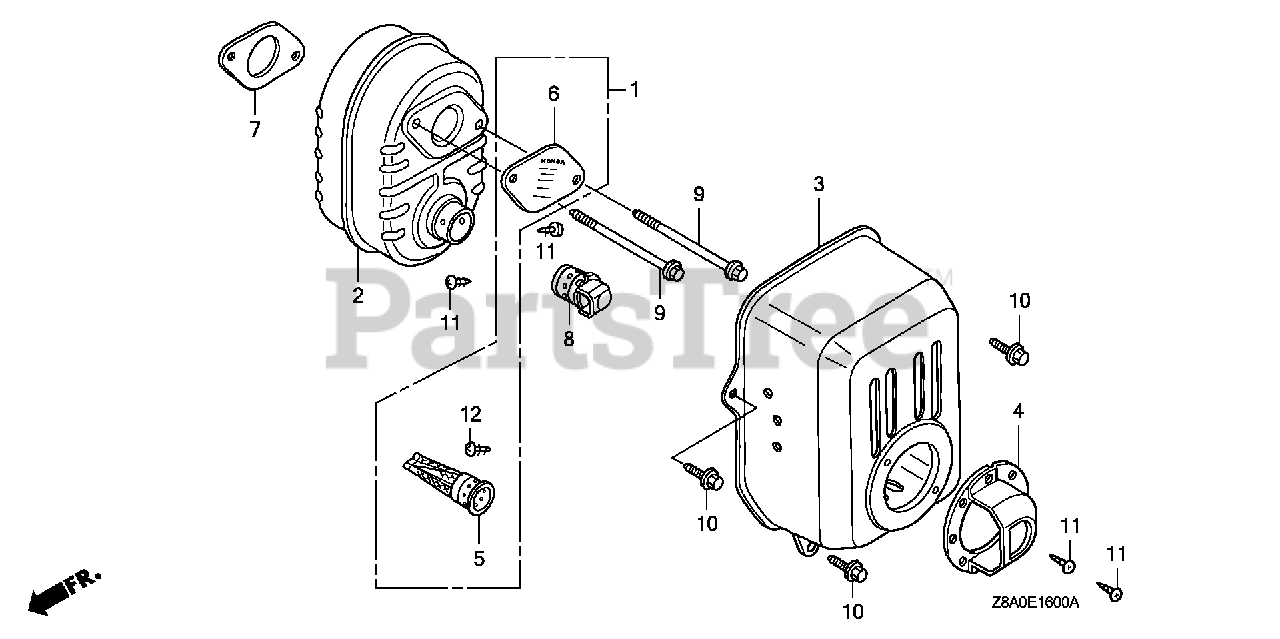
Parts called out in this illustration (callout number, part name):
1	ARRESTER KIT, SPARK
3	PROTECTOR, MUFFLER
5	ARRESTER, SPARK
6	PLATE, ARRESTER NUMBER
7	GASKET, MUFFLER
9	BOLT, FLANGE (6X79) (CT200)
10	BOLT, FLANGE (6X12) (CT200)
12	SCREW, TAPPING (4X6)
